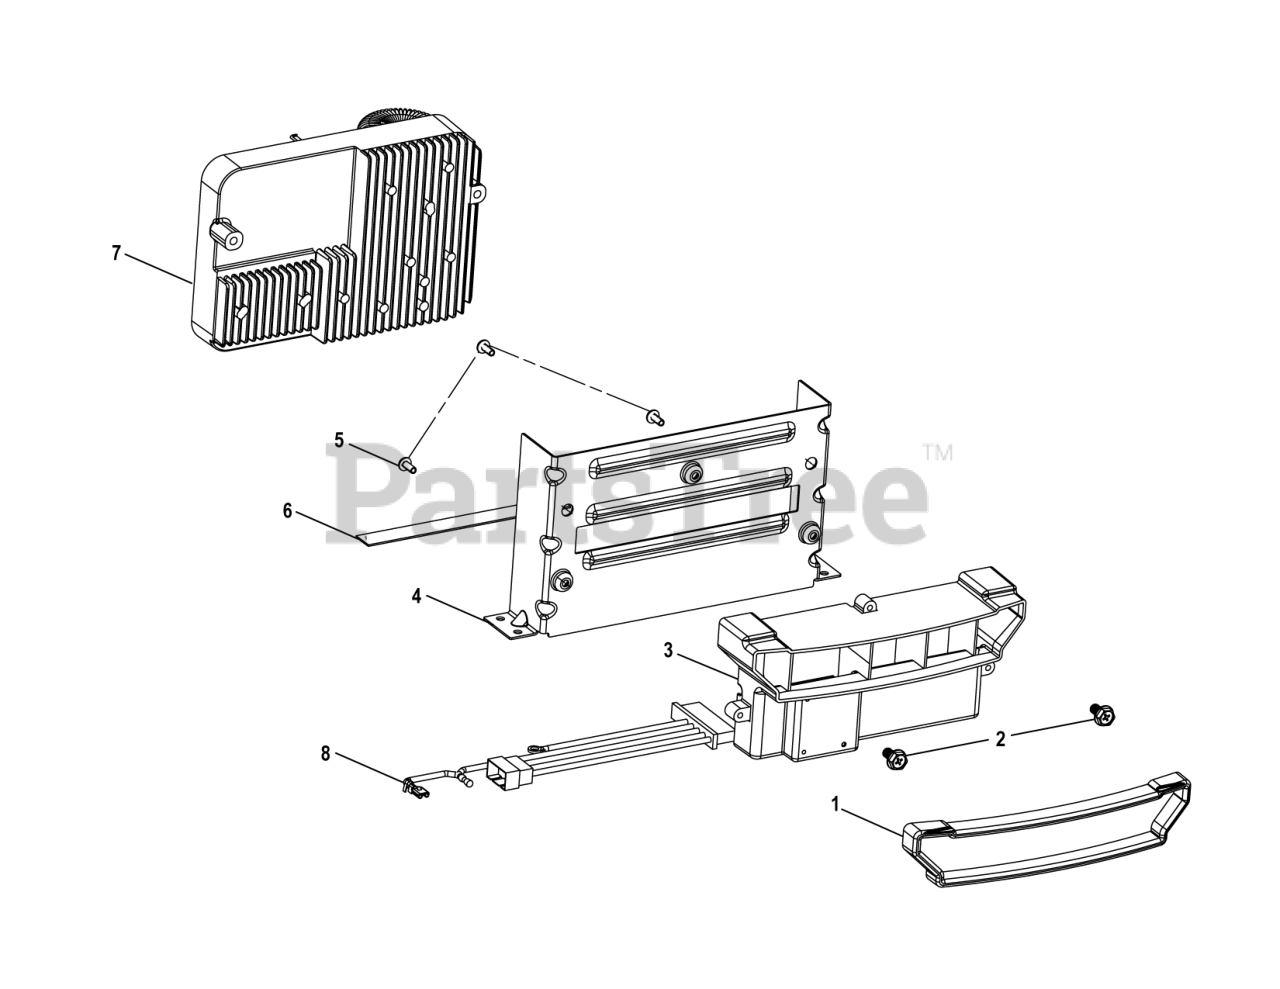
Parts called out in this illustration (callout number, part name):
1	TRIM, RUBBER
3	ASSY., BAFFLE
4	BRACKET, INVERTER MODULE
5	SCREW W/WASHER
6	RUBBER PAD
7	MODULE, INVERTER
8	HARNESS, CO MODULE
